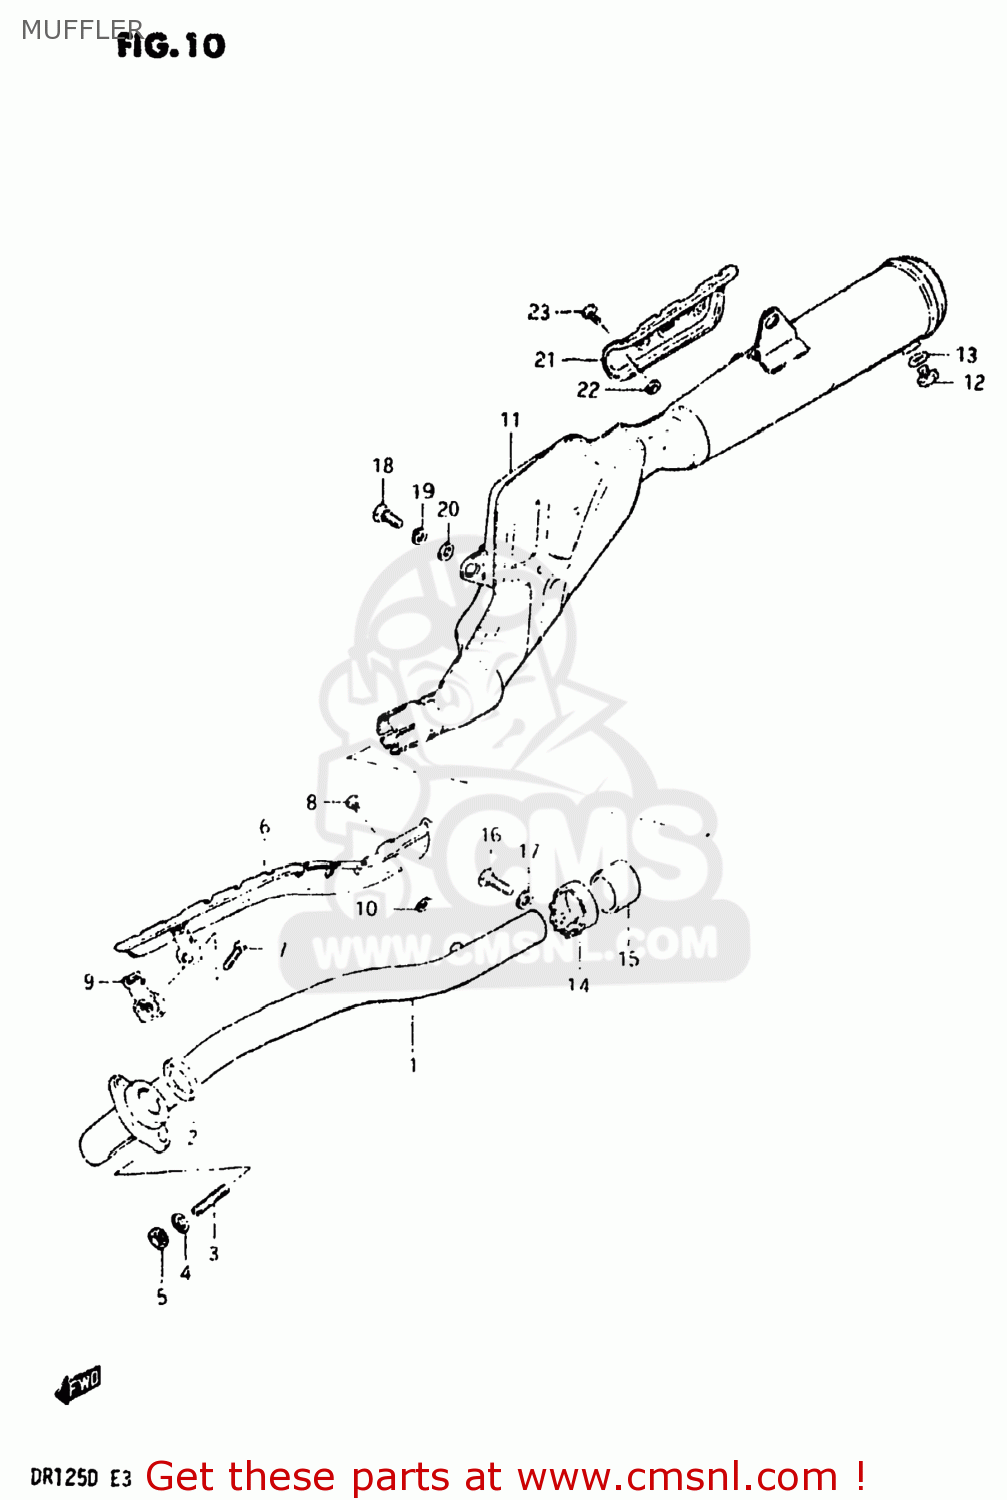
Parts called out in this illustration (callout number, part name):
1	PIPE,EXHAUST
2	GASKET,EXHAUST PIPE (NAS)
3	STUD BOLT L:20
4	LOCK WASHER
5	NUT
6	COVER,EXHAUST PIPE
7	SCREW 5X20
8	SCREW
9	CLAMP,EXHAUST PIPE COVER
10	GASKET 6.2X12X1.5 (MCA)
11	MUFFLER ASSEMBLY
12	PLUG(12X9)
13	GASKET(12X16X2) (NAS)
14	CLAMP,MUFFLER CONNECTOR
15	CONNECTOR,MUFFLER
16	BOLT 8X35
17	WASHER,8.5X16X
18	BOLT
19	LOCK WASHER
20	WASHER,8.5X16X
21	COVER,MUFFLER
22	GASKET 6.2X12X1.5 (MCA)
23	SCREW
